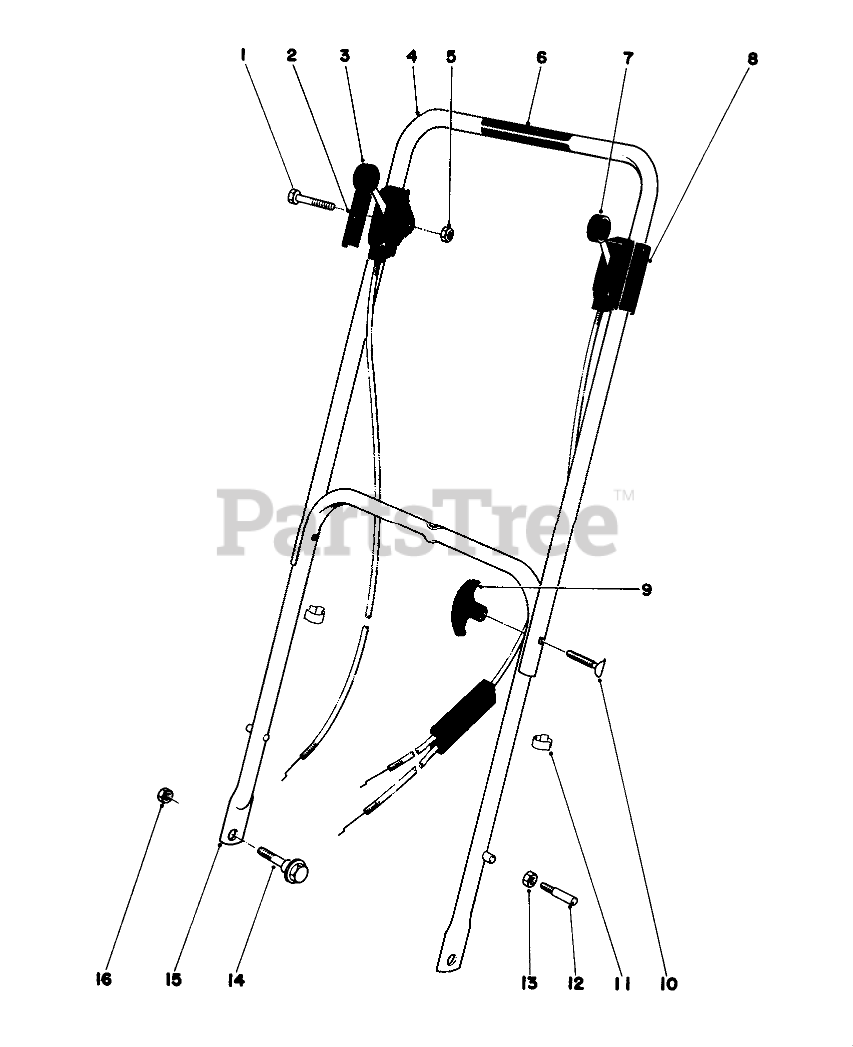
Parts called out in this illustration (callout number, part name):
1	SCREW-HH
2	Decal-Throttle
3	Throttle Control
4	Upper Handle
5	NUT-LOCK
6	Decal
7	Traction Control
8	Decal-Traction Control
10	HANDLE SCREW
11	BOWDEN CLIP
12	HANDLE PIN
13	Nut
14	SCREW-SHOULDER
15	Lower Handle
16	Nut
